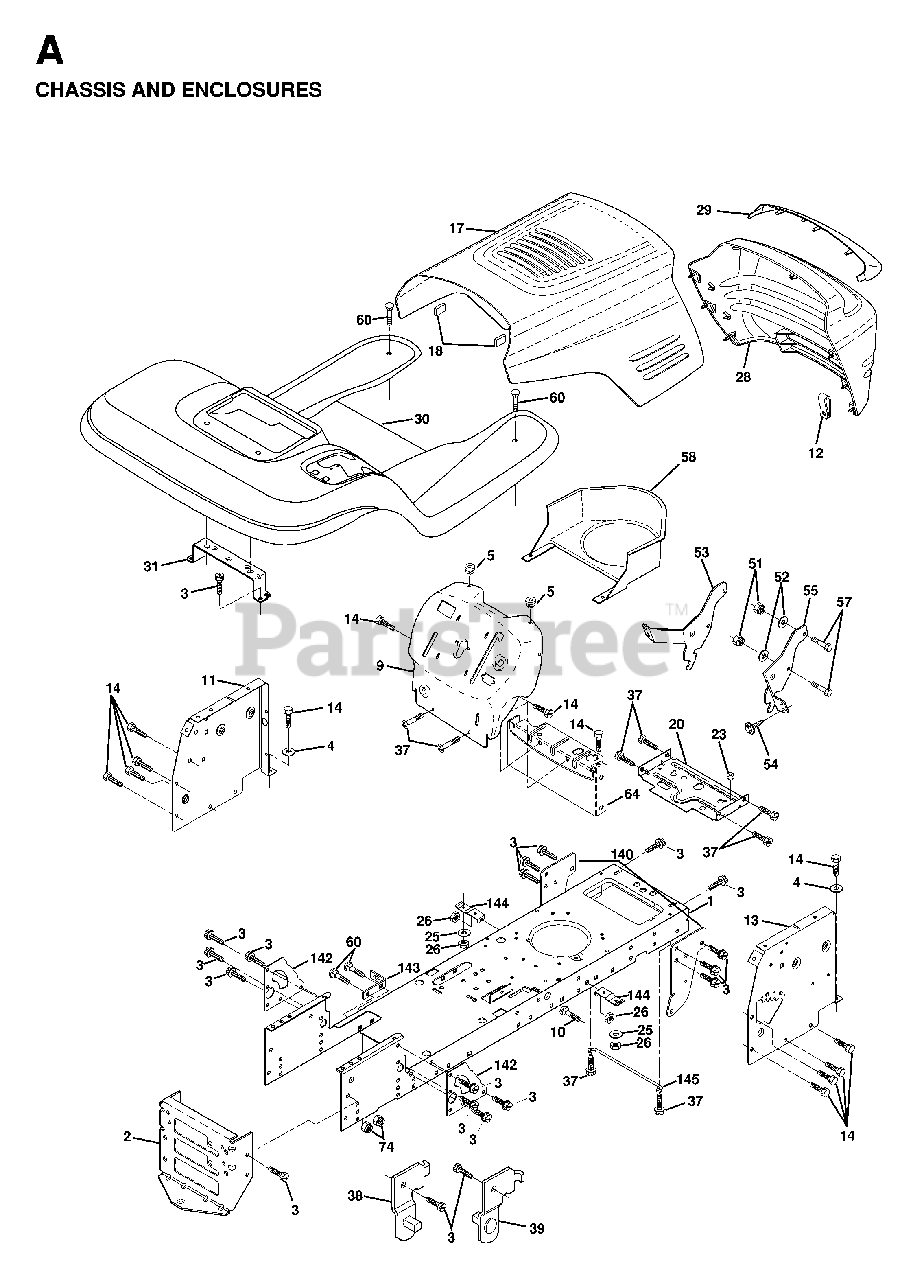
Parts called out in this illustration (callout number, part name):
2	STRETCH DRAWBAR
3	SCREW
5	BUMPER.RUBBER.HOOD
10	BOLT D
11	PANEL DASH LH
13	DASH PANEL
18	BUMPER HOOD T
20	PLATE MTG
23	GROMMET T
25	WASHER
26	NUT
38	BRACKET LH PIVOT
39	BRACKET RH PIVOT
51	LOCKNUT
57	BOLT
58	AIR DUCT P/L/LT
64	DASH LOWER
74	LOCKNUT
140	BRACKET SUSPENSION FRONT
142	PLATE REINFORCEMENT
143	BRACKET, SWAY BAR
144	BRACKET FOOTREST
145	ROD PIVOT CHASSIS/HOOD
